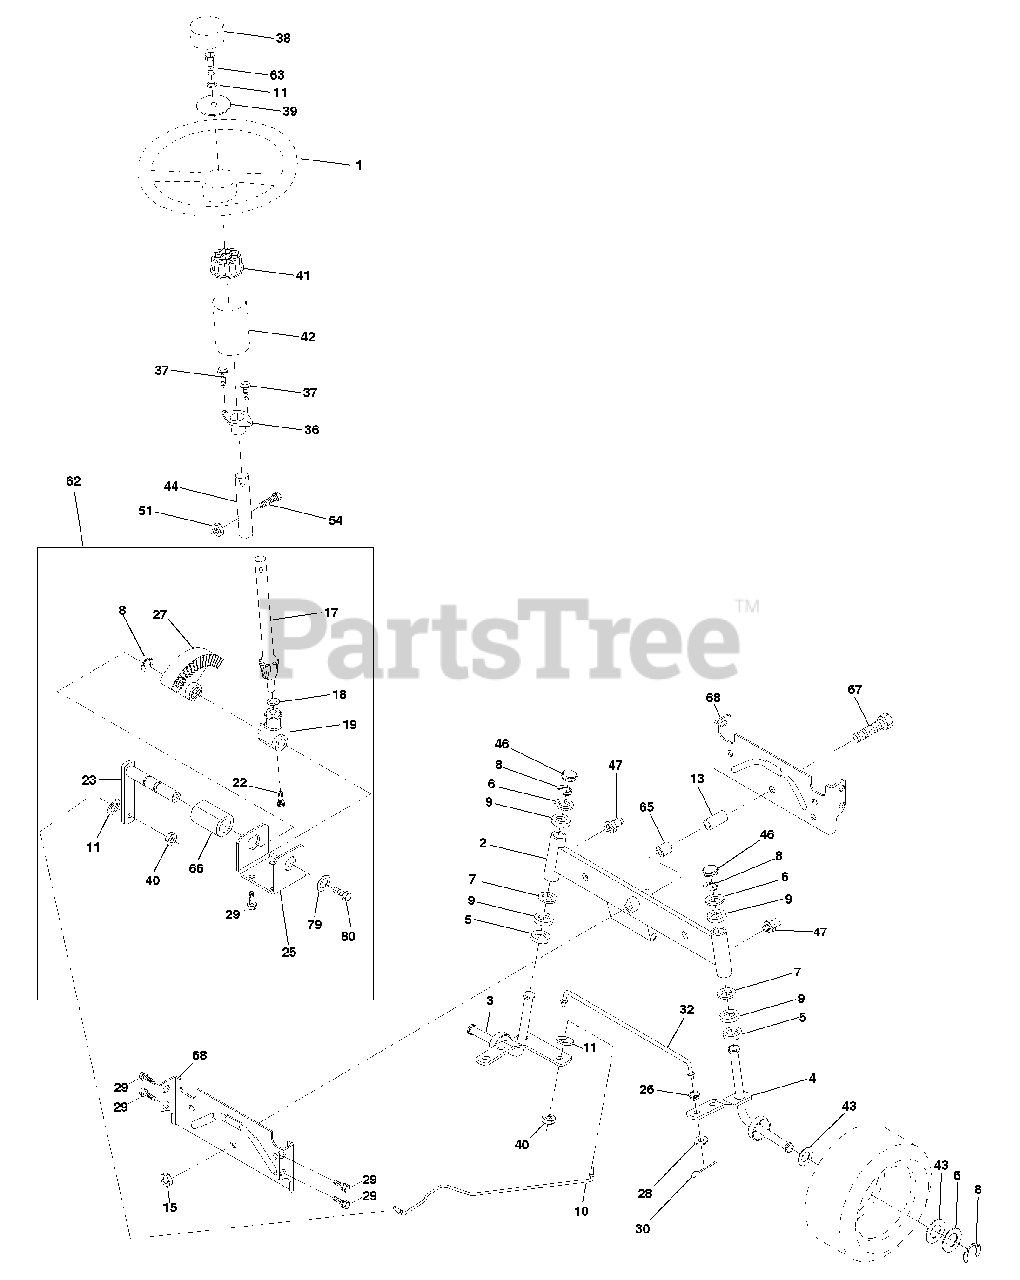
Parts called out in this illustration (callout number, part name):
1	Wheel Steering Ayp/P/L Blk
2	Axle Asm
3	Spindle Asm LH
4	Spindle Asm RH
5	Bearing Race Thrust Harden
6	Washer 25/32 X 1-5/8 X 16 Ga
7	Washer 27/32 X 1-1/4 X 16 Ga
8	Ring Klip #t5304-75
9	Bearing Col Strg Blk
10	Link Drag Extended Stamped
11	Washer Lock Hvy Hlcl Spr 3/8
13	Bearing Axle
15	Nut Lock Flange 5/8-11 Unc
17	Shaft Asm Strg
18	Washer Thrust 515x 750x 033
19	Support Shaft
20	Washer Shim 1/4 X 5/8 X 062
22	Screw Hex Socket 1/4-20 x 5/8
23	Shaft Asm Pittman
25	Bracket Steering
26	Bushing Link Drag Blk LR
27	Gear Sector
28	Washer 13/32 X 7/8 X 16 Ga
29	Screw Thdrol 3/8-16x3/4 Ty-tt
30	Pin Cotter 1/8 X 3/4 Cad
32	Rod Tie Wire Form 19 75 Mech
36	Bushing Strg 5/8 Id Dash
38	Cap Wheel Steer Ayp
39	Washer 13/32 X 2-3/8 X 8 Ga
40	Nut Lock Center 3/8-24 un
41	Adaptor Wheel Strg
42	Boot Dash Mtl Steering Blk
43	Washer 25/32 X 1 1/4 X 16 Ga
44	Extension Steering
46	Cap Spindle Fr Top Blk
47	Fitting Grease
51	Nut Lock Hex W/Ins 5/16-18
54	Bolt Fin Hex 3/8-16unc x 1-1/4
62	Kit Steering Assembly Service
63	Bolt Fin Hex 3/8-16unc x 1 Gr.5
65	Spacer Axle
66	Bearing Arm Pittman
67	Bolt Fin Hex 5/8-11 unc x 2-3/4
68	Brace Axle
